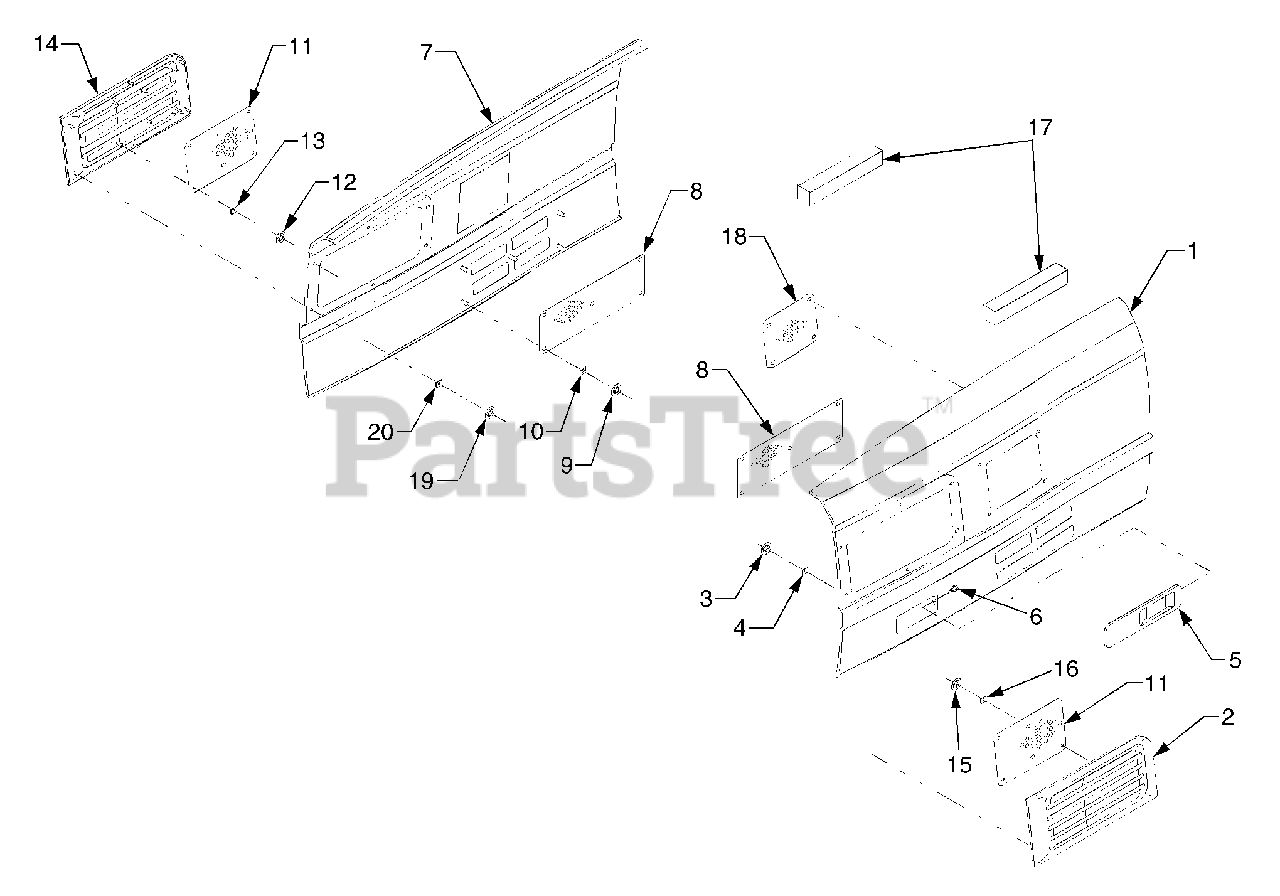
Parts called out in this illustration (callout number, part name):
1	Cover, Side (LH)
2	Grill, Side Cover (LH)
4	Rubber, Stopper
5	Cover, Muffler
7	Cover, Side (RH)
8	Net, Side Cover
10	Rubber, Stopper
13	Rubber, Stopper
14	Grill, Side Cover (RH)
16	Rubber, Stopper
18	Net, Side Cover
20	Rubber, Stopper
